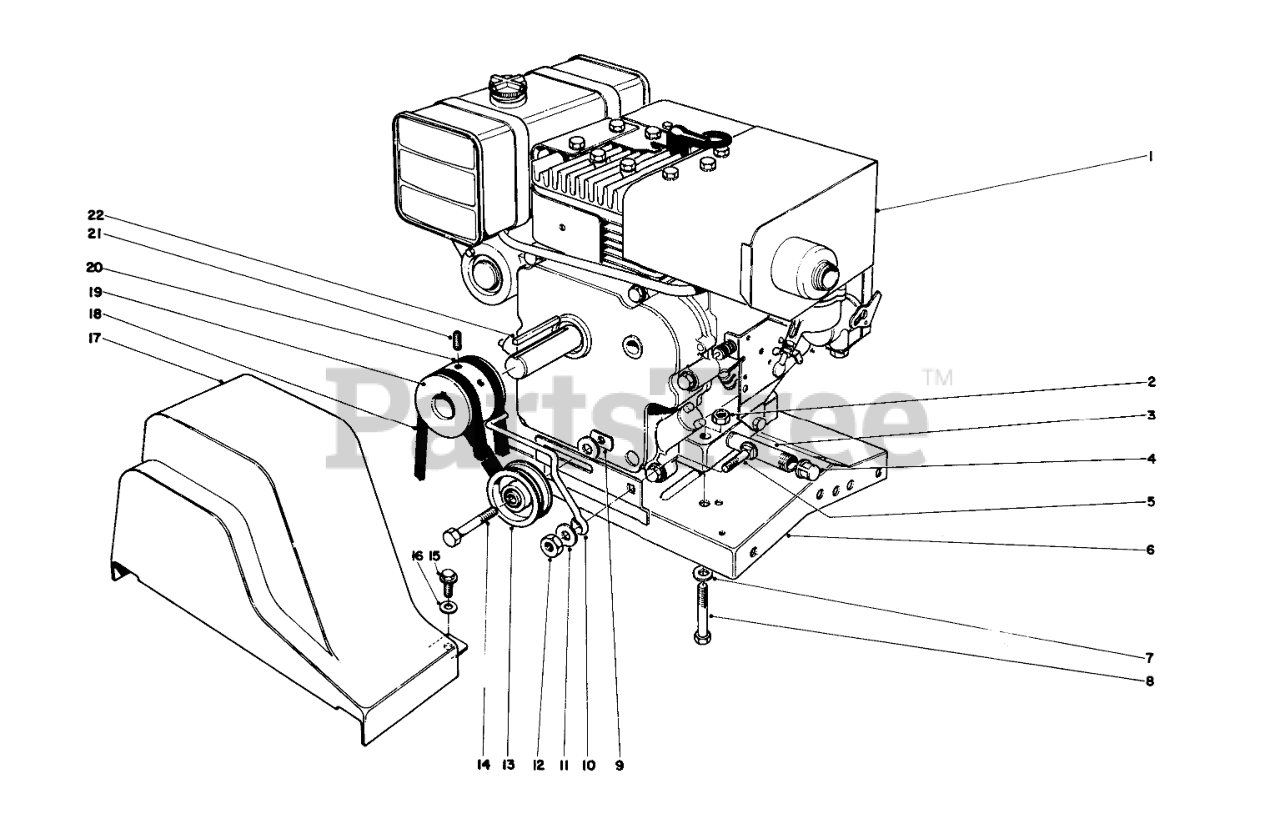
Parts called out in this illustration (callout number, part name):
1	Engine
2	Nut
3	NIPPLE-PIPE
4	CAP-PIPE
5	SCREW-CARR
6	Engine Base
7	WASHER-FLAT
8	SCREW-HH
9	Weldnut
10	BELT GUIDE
11	WASHER-FLAT
12	NUT-HEX
13	PULLEY-IDLER
14	SCREW-HH
15	Screw, Self-tapping
16	WASHER-FLAT
17	BELT GUARD
18	V-Belt
19	Pulley
20	V-BELT
21	Screw-Set
